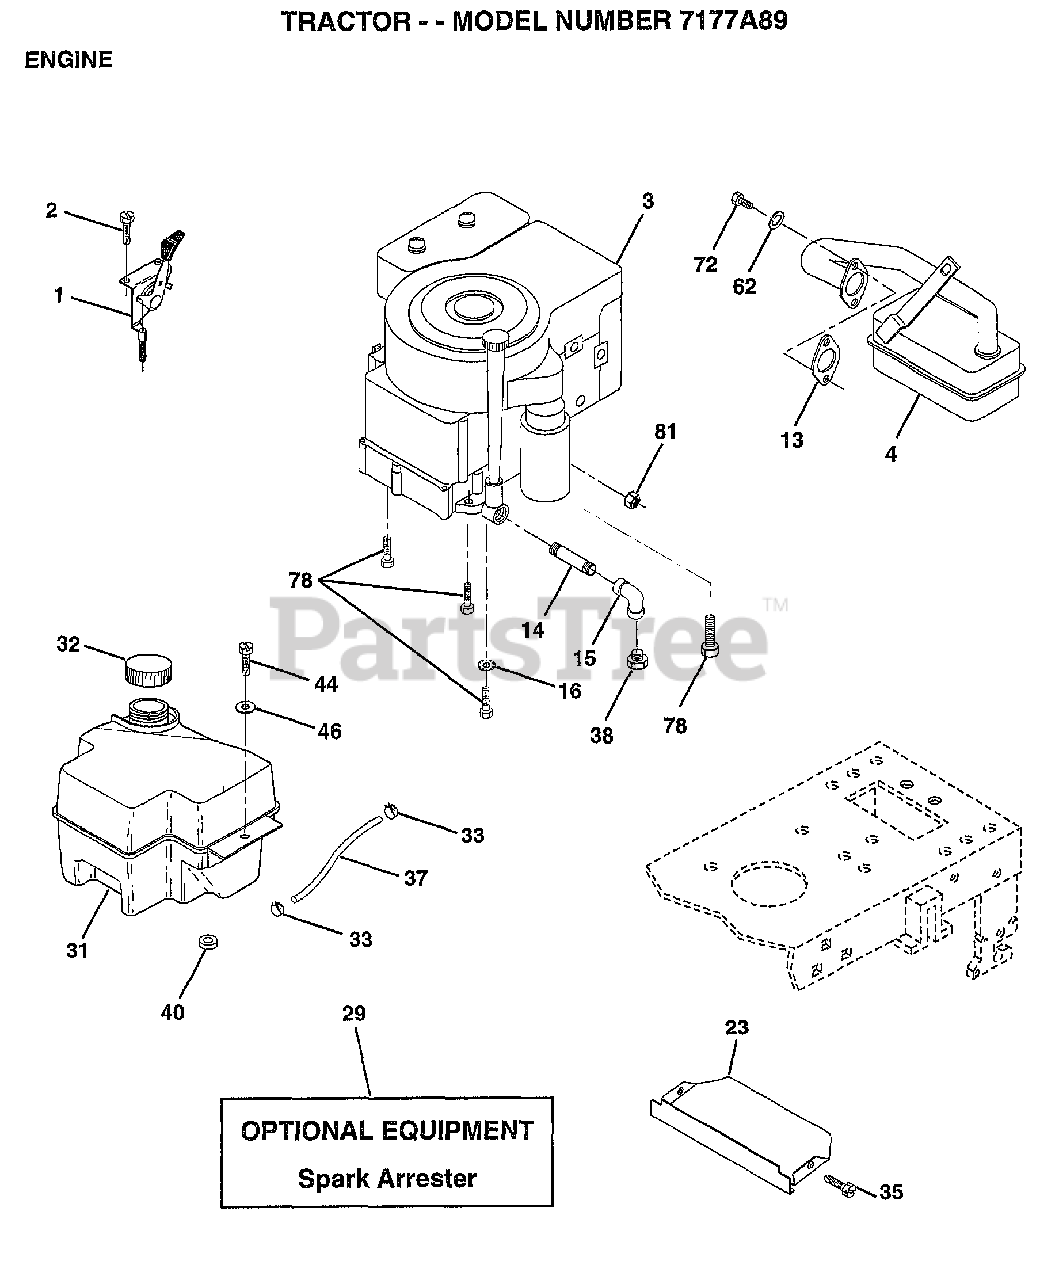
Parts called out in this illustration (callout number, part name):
1	CONTROL THROTTLE
2	SCREW LT
4	MUFFLER
13	GASKET ENG 1 313 LD TIN PLATED
14	PIPE NIPPLE
15	ELBOW
16	LOCKWASHER
23	SHIELD.BRN/DBR.GD
31	TANK.FUEL.FRONT.
32	CAP ASM FUEL
33	HOSE CLAMP
35	SCREW
37	LINE FUEL
44	SCREW HEX CRT
46	WASHER
62	LOCKWASHER
72	SCREW
78	SCREW
81	NUT
